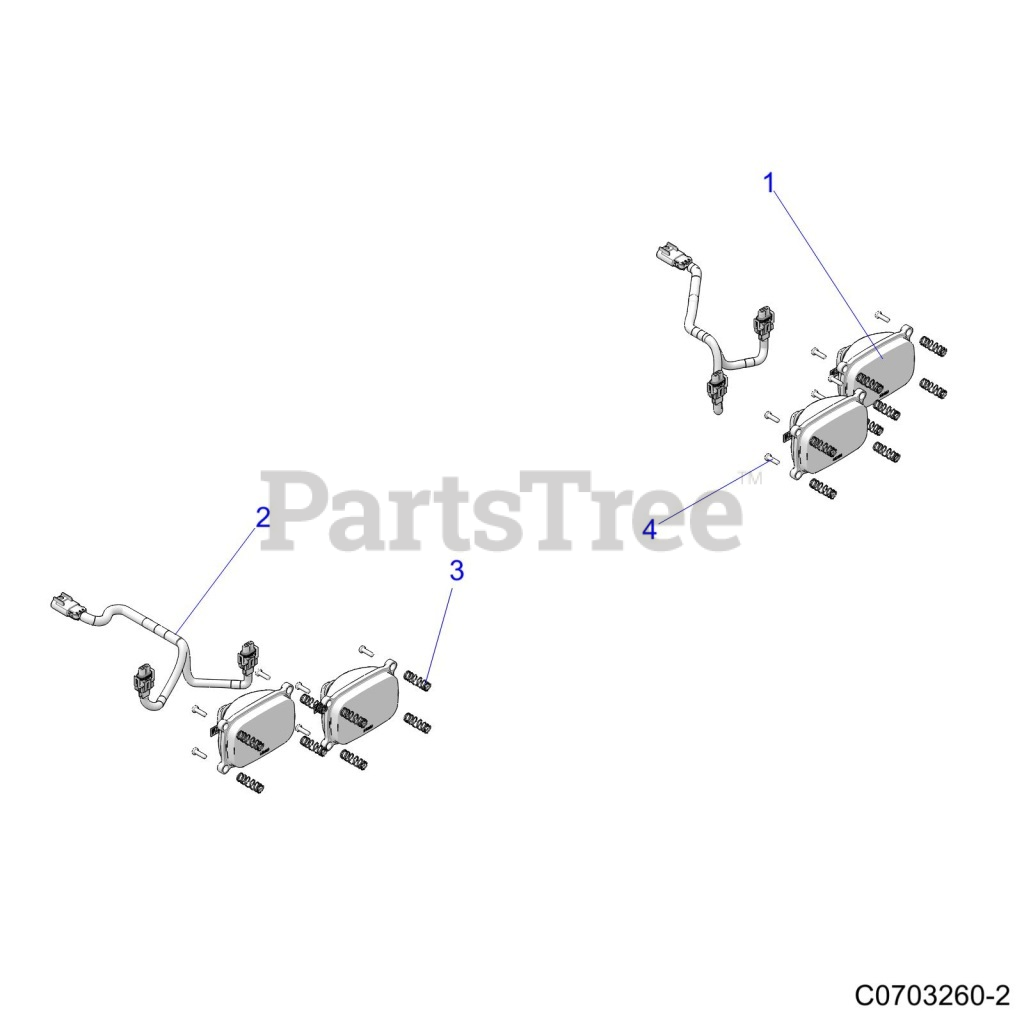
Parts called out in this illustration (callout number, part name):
1	ASM-HEADLIGHT
2	HARNESS-HEADLIGHT,ARNS
3	SPRING, HEADLIGHT
